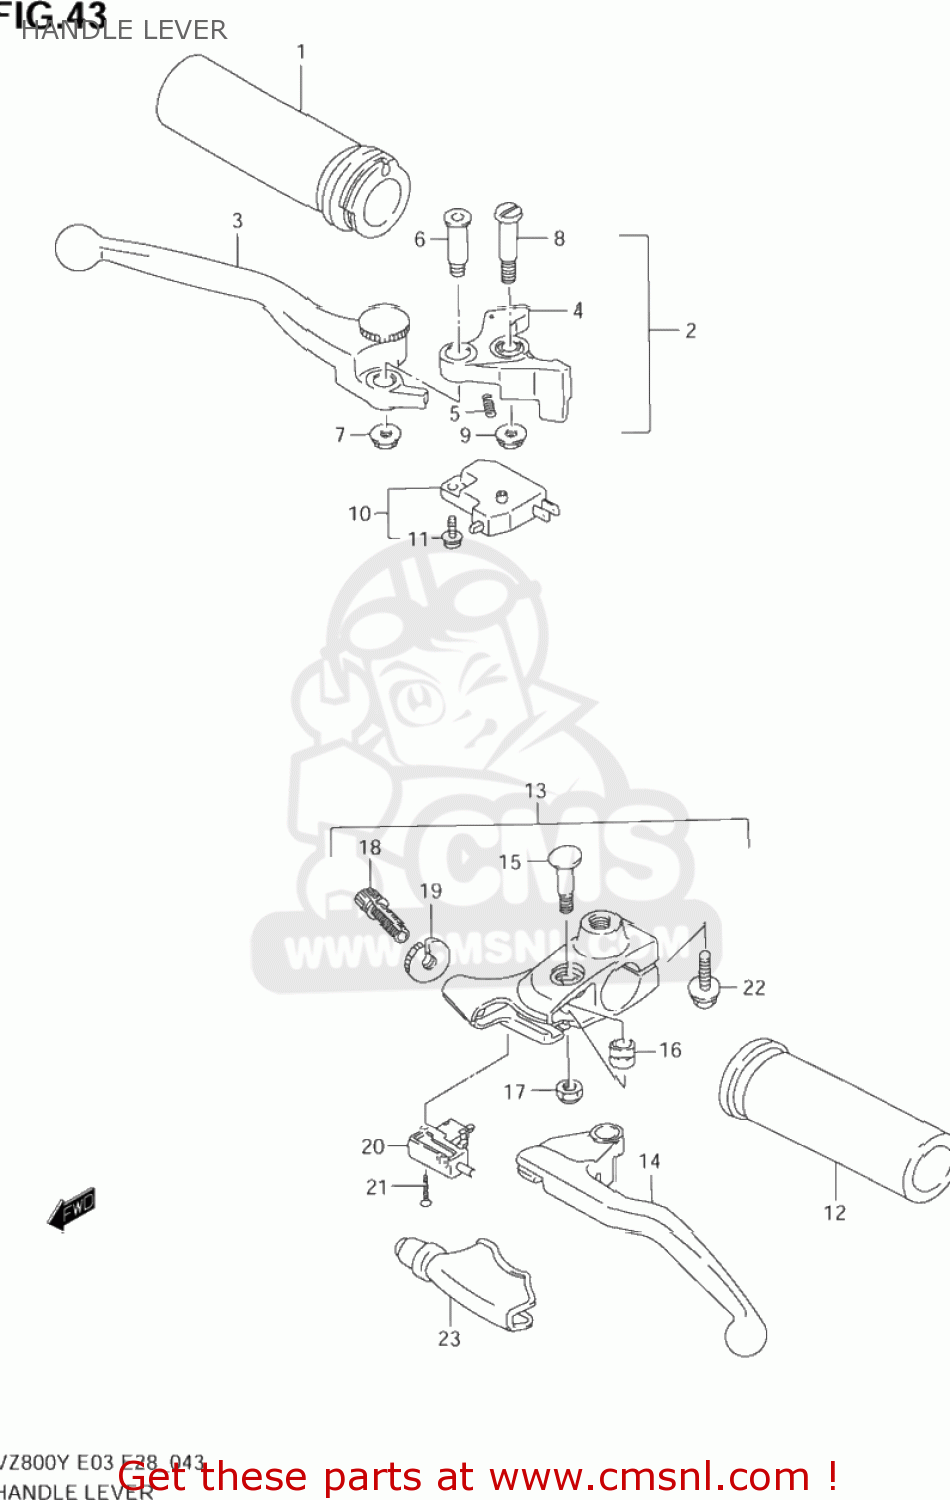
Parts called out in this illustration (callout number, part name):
1	GRIP,THROTTLE
2	LEVER ASSY,BRAKE
3	LEVER,ADJUST
4	KNOCKER
5	SPRING
6	BOLT,LEVER
7	NUT
8	BOLT,LEVER PIVOT
9	NUT
10	SWITCH ASSEMBLY,STOP
11	SCREW
12	GRIP,L
13	LEVER ASSY,CLUTCH
14	LEVER,CLUTCH
15	BOLT,CLUTCH LEVER
16	SPACER,CLUTCH LEVER PIVOT
17	NUT 6MM
18	ADJUSTER,WIRE
19	NUT,LOCK
20	SWITCH,CLUTCH
21	SCREW
22	BOLT
23	COVER,CLUTCH LEVER
